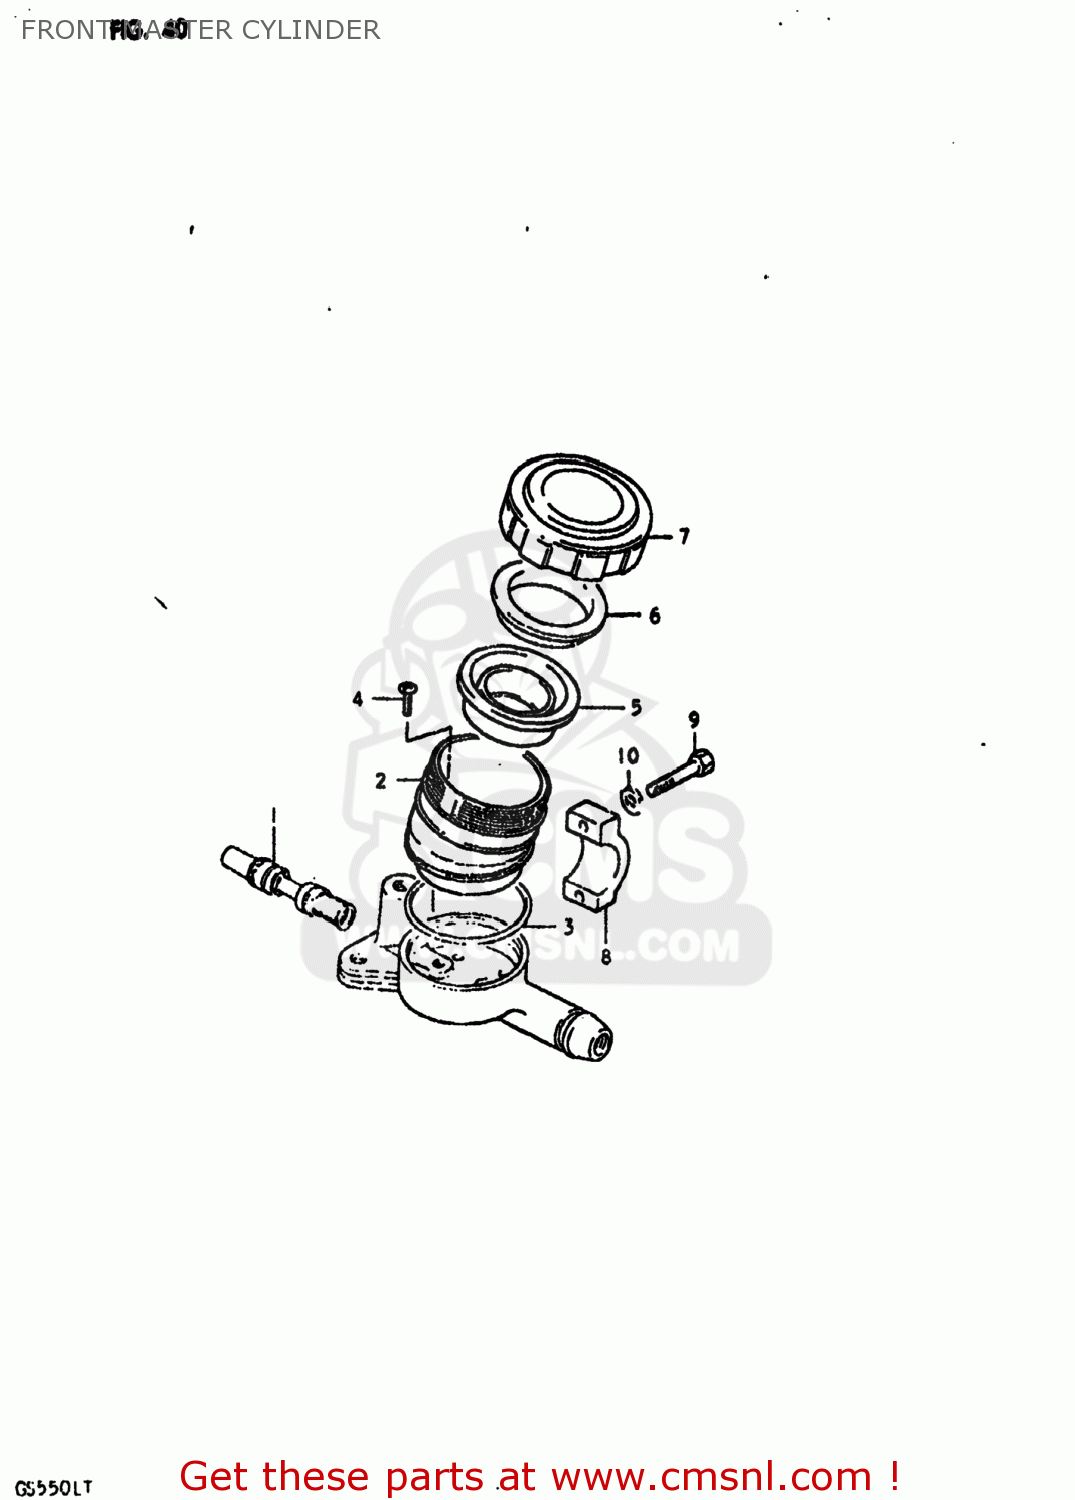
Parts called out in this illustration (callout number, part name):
1	PISTON & CUP SET
2	RESERVOIR
3	O RING
4	SCREW,MASTER CYLINDER
5	DIAPHRAGM
6	PLATE
7	CAP,MASTER CYLINDER,REAR
8	HOLDER,MASTER CYLINDER
9	BOLT
10	WASHER
